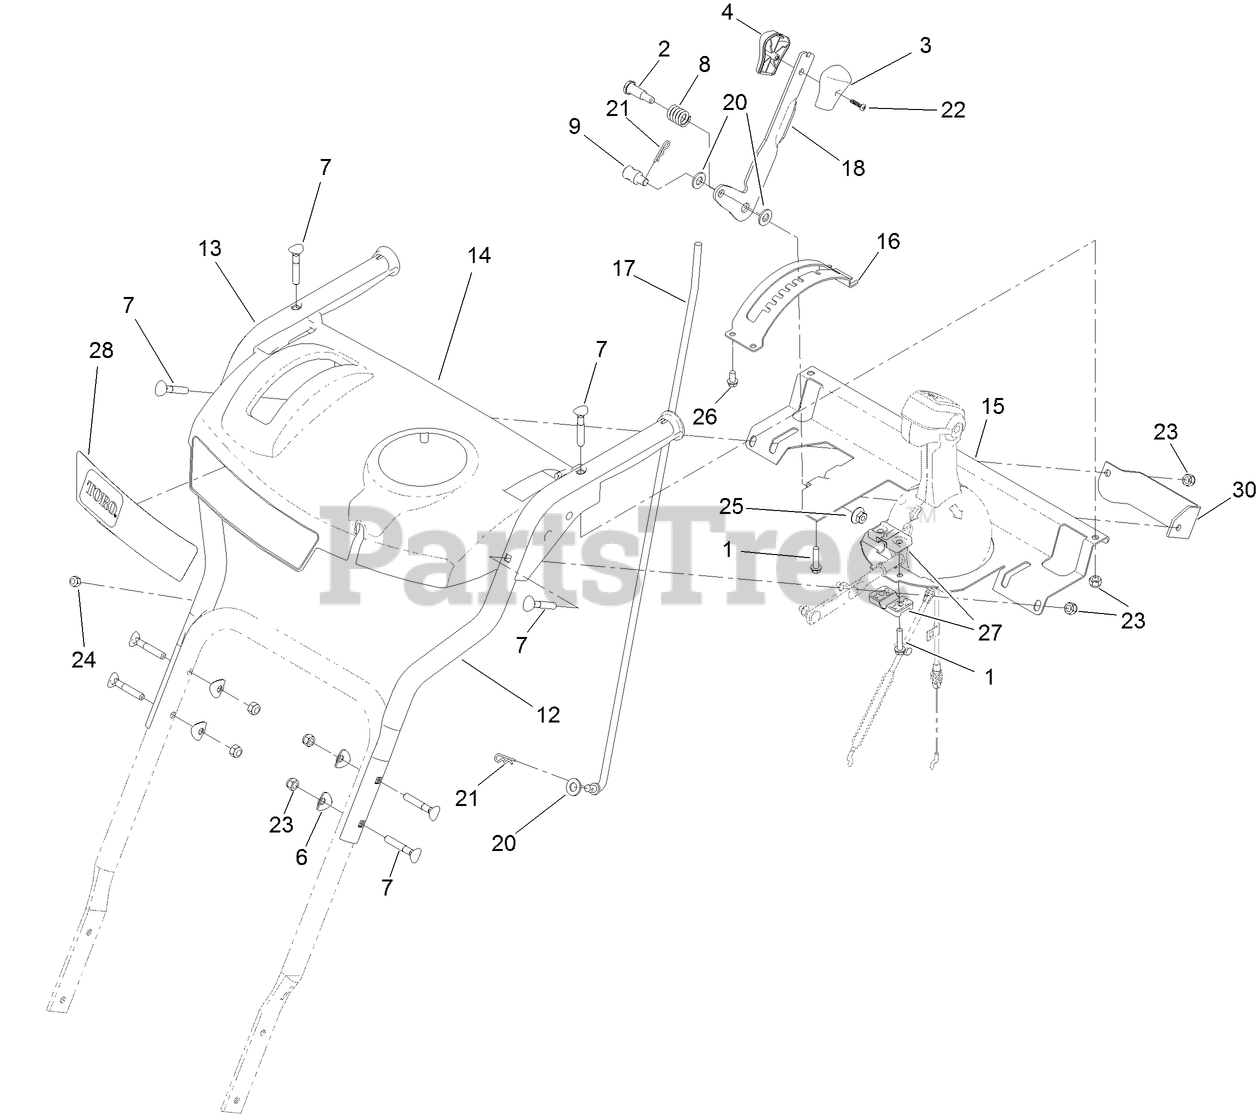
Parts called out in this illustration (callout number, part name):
1	SCREW-PLASTITE, HWH
2	SCREW-SHOULDER, HH
3	KNOB-SHIFT, LH
4	KNOB-SHIFT, RH
6	WASHER-CUP
7	SCREW-HANDLE
8	SPRING-COMPRESSION
9	TRUNNION-ROD
12	HANDLE-UPPER, LH
13	HANDLE-UPPER, RH
14	PANEL-CONTROL, MASTER
15	SUPPORT-PANEL, CONTROL
16	MOUNT-SELECTOR, SPEED
17	ROD-SELECTOR, GEAR
18	SELECTOR-SPEED
20	WASHER-THRUST
22	SCREW-PPH
26	SCREW-PLASTITE
27	SUPPORT-ROD
28	DECAL-MODEL
30	PLATE-SUPPORT, SHIFT
